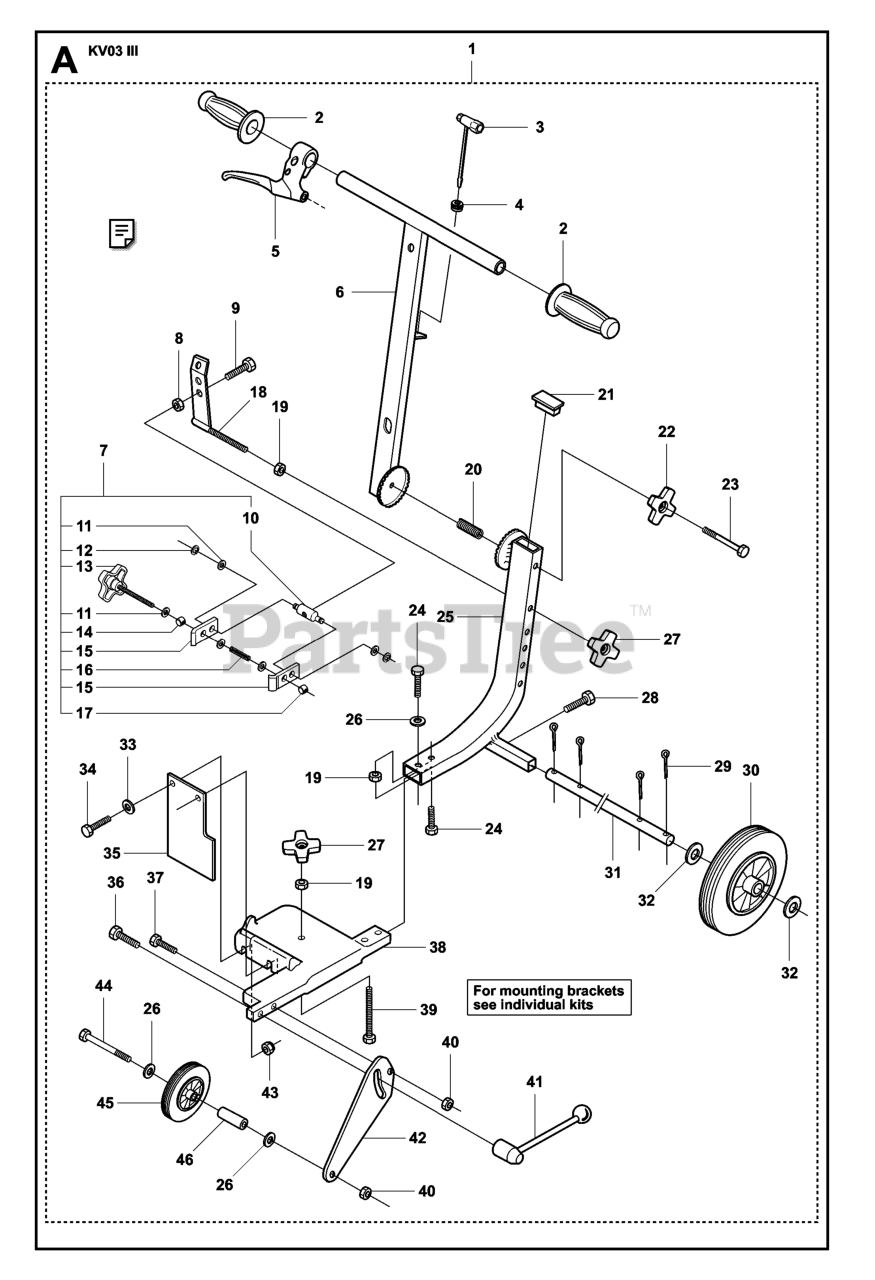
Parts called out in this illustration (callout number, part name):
1	CUTTING TROLLEY
4	ANTIVIBE ELEMENT
5	HANDLE-TRIGGER
8	NUT
11	WASHER - M6
13	STEERING WHEEL
19	NUT
20	COMPRESSION SPRING
22	STEERING WHEEL
25	FRAME WELDMENT
26	WASHER - 25X8.5X2.3
28	SCREW 8X20
34	Slotted Truss Head Screw #10-32 x 5/8"
35	Splash Guard
38	COUNTERWEIGHT
40	LOCKNUT M8
41	Lock Handle
44	SCREW M8 X 70
46	SPACING SLEEVE
